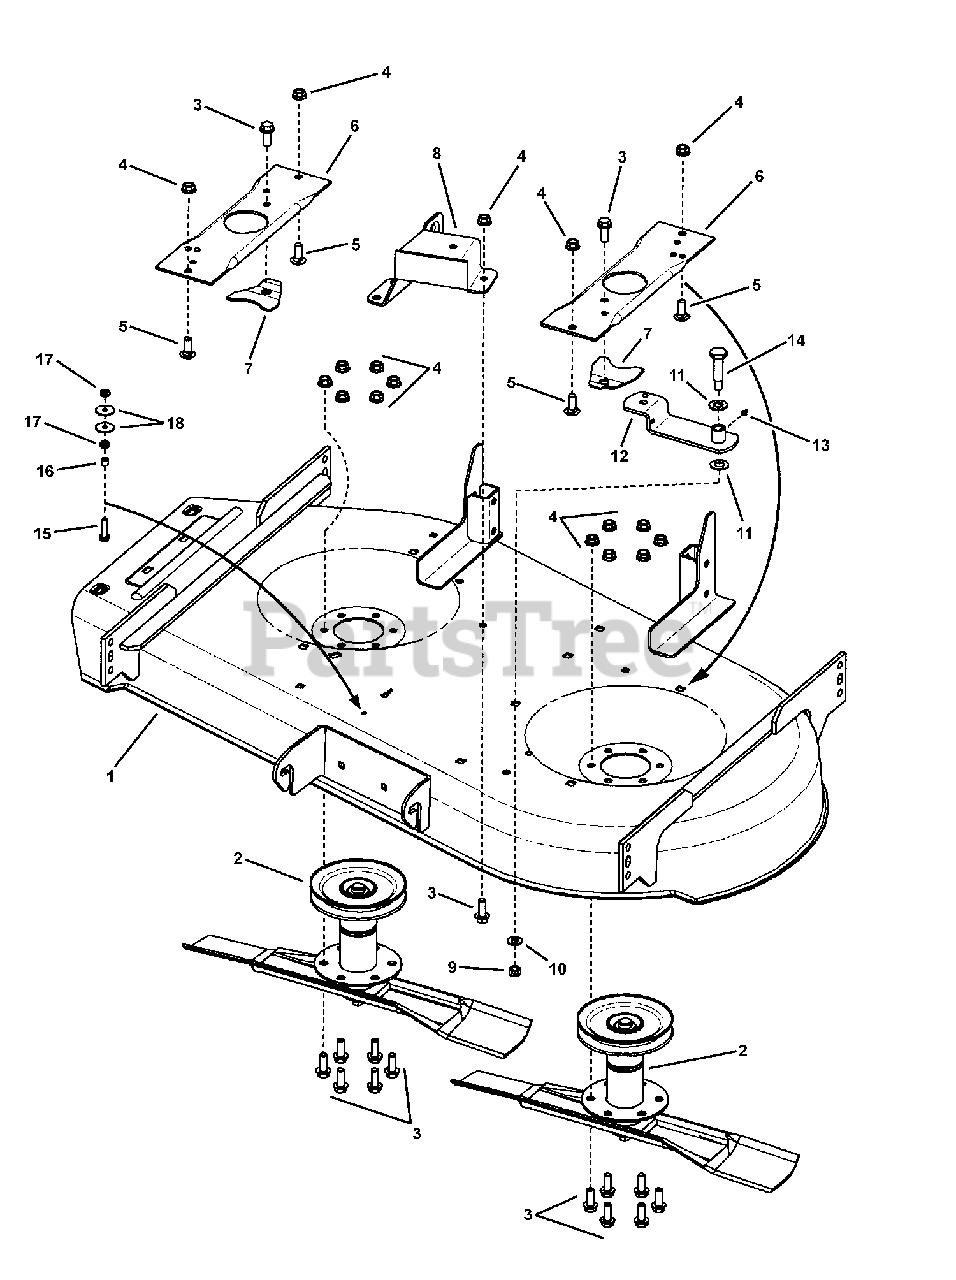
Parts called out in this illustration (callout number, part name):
1	WELDMENT, 42" Deck
2	ASSEMBLY, Spindle Brake
3	BOLT, 3/8-16 x 1" Hex Flange Lock, GR 5
4	NUT, 3/8-16 Hex Flange Lock
5	BOLT, 3/8-16 x 1" Square Neck Carriage, GR 5, YZ
6	SPINDLE BRACE
7	ASSEMBLY, Spindle Lock
8	WELDMENT, Stationary Idler 42"
9	NUT, 3/8-24 Hex Center Lock
10	WASHER, 3/8" Flat SAE
11	WASHER, .531 x 1.0 x .063 Flat
12	WELDMENT, Idler Arm, 38" RZT (Cardinal Red)
13	LUBE FITTING, 3/16"
14	SHOULDER BOLT, 3/8-24 x 5/8" YZ
15	BOLT,1/4-20 x 1-1/8" Hex Flange Lock, GR 5
16	SPACER, .265 I.D. x .375 O.D. x .300 thick
17	NUT 1/4-20 Hex Center Lock, GR 5 YZ
18	WASHER, .27 x 1.0 x .065 Flat
